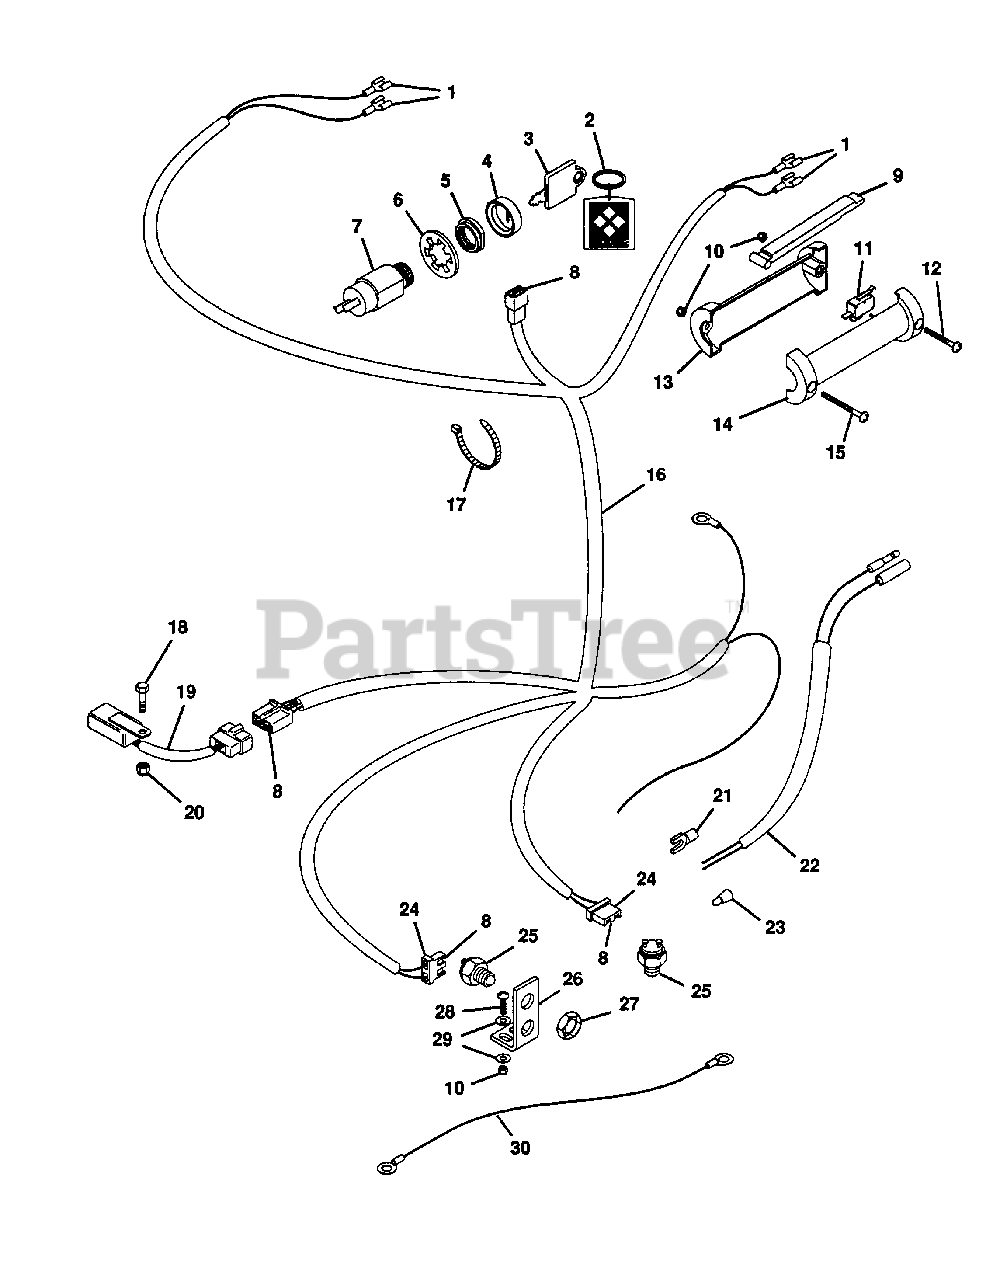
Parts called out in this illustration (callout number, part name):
1	TERMINAL, FEMALE
2	CHAIN, KEY
3	KEY, IGNITION SWITCH
4	BOOT, FOR 9/16 SWITCH
5	NUT, 5/8-32 FOR SWITCH
6	WASHER, LOCK 5/8 INT. TOOTH
7	SWITCH, IGNITION
8	TERMINAL
9	LEVER
10	NUT, LOCK 10-24
11	SWITCH
12	SCREW, MACHINE 10-24X.625 PHD
13	HANDLE, R.H.
14	HANDLE, L.H.
15	SCREW, MACH. 10-24X1.50 PHDCR
16	HARNESS, WIRING
17	TIE WRAP, BLACK
18	BOLT, HEX 1/4-20X.750
19	MODULE, INTERLOCK
20	NUT, LOCK 1/4-20
21	TERMINAL, PRE-INSULATED
24	CONNECTOR, 2-WIRE SWITCH
25	SWITCH, NEUTRAL START
26	BRACKET, INTERLOCK SWITCH
27	NUT, STAMPED 9/16-18
28	SCREW, MACHINE 10-24X.75 PHD
29	WASHER, FLAT .188X.438X.049
30	WIRE, GROUND
